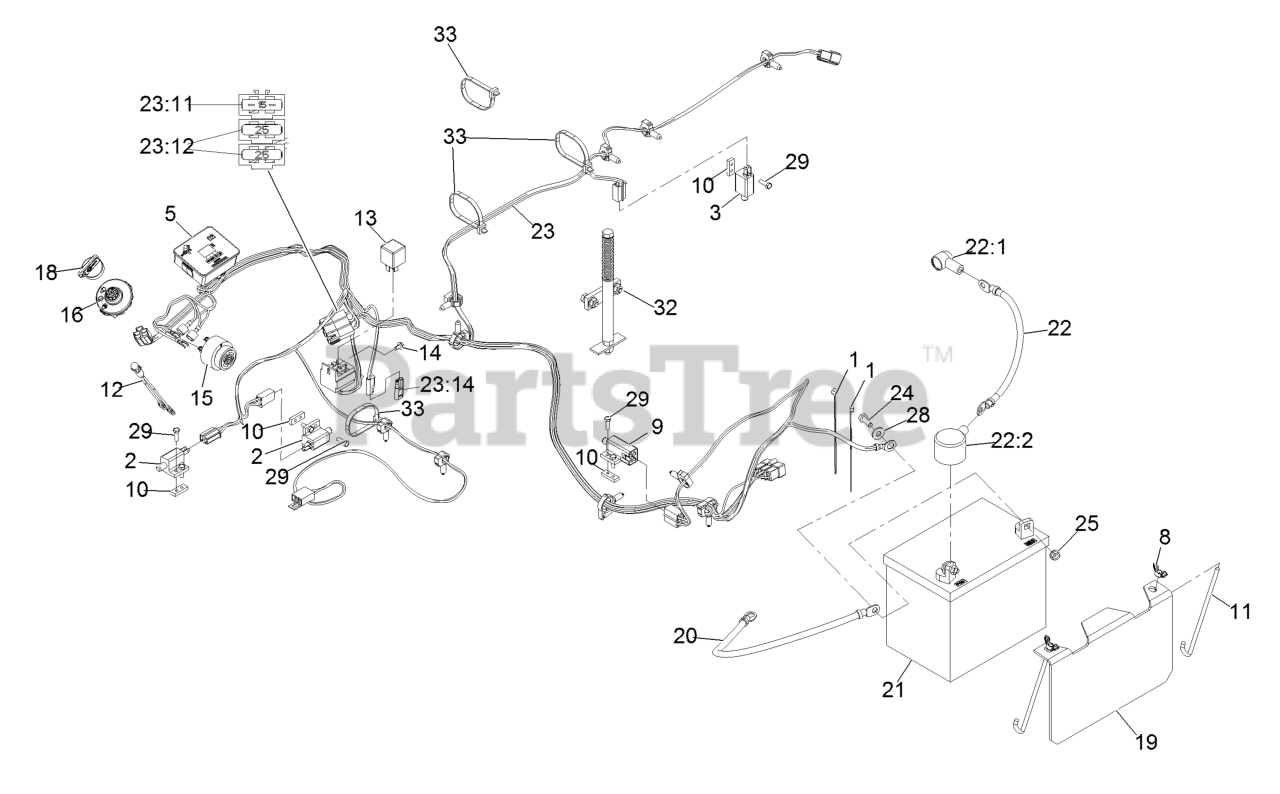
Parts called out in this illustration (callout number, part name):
1	Tie-Cable 5 1/2 (Small)
2	Switch-N.O.
3	Switch-N.C.
5	Hour Meter ASM
8	Wingnut-Nyloc 1/4-20
10	Plate-Tapped
11	Bolt-Holddown
12	Indicator-Red LED
13	Relay-12Vdc 40 Amp
14	Screw-HWH #10-24 X 3/8
15	Alarm-Dual Tone 12Vdc
16	Switch-Ignition
18	Key-Exmark Logo
19	Hold Down-Battery
20	Cable-Ground(-)
21	Battery (300 CCA, Wet)
22	Cable-Battery, Positive
22:1	Insulator-Solenoid
22:2	Insulator-Battery
23	Harness-Wiring
23:11	Fuse-Blade, 15 Amp
23:12	Fuse-Blade, 25 Amp
23:14	Cap-Plug
24	Screw-HH 1/4-20 X 3/4
25	Nut-Whizlock 1/4-20
28	Washer-1/4 Std
29	Screw-HH Machine 10-24 X 5/8
32	Hopper Switch Actuator ASM
33	Tie-Cable 7 15/16 (Large)
